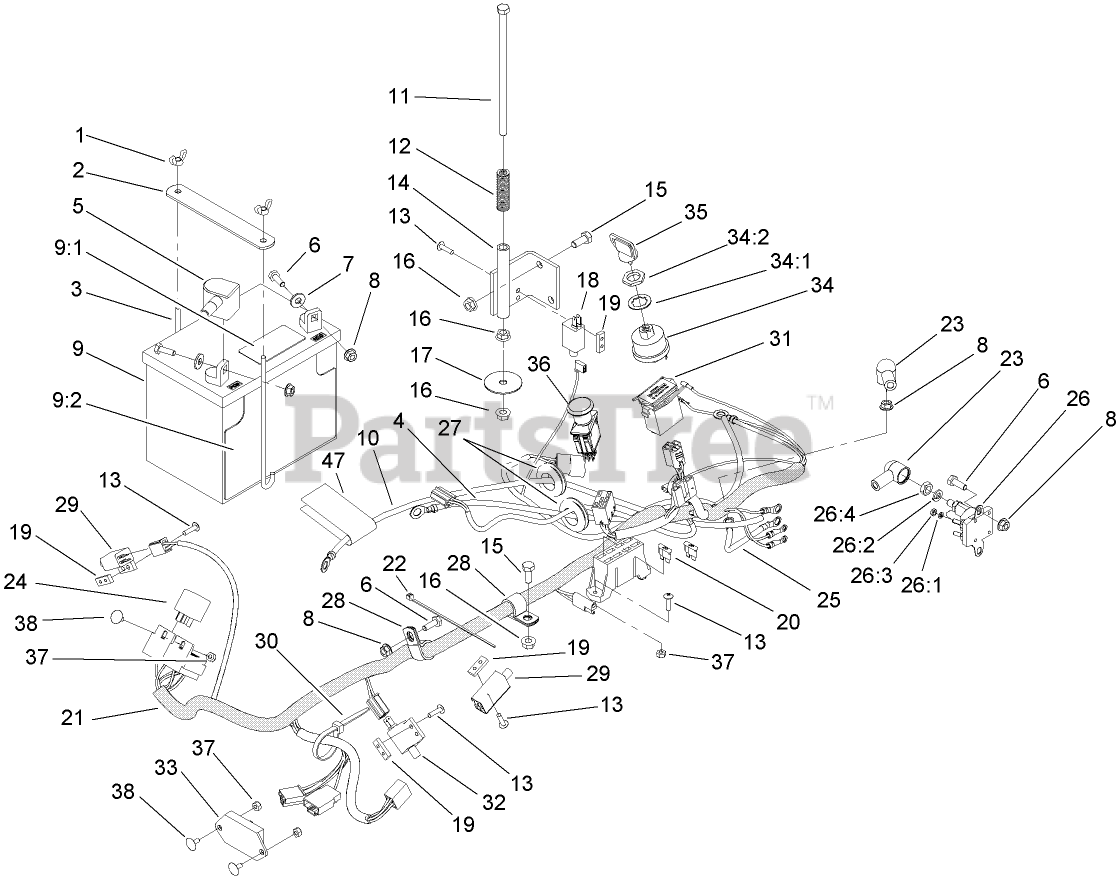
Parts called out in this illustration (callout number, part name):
1	WINGNUT
2	STRAP-HOLDDOWN, BATTERY
3	BOLT-HOLDDOWN
4	CABLE-GROUND, NEGATIVE
5	INSULATOR-BATTERY
6	SCREW-HH
7	WASHER-FLAT
8	NUT-HF
9	BATTERY
9:1	Decal-Battery
9:2	Decal-Battery
10	CABLE-BATTERY, POSITIVE
11	SCREW-HH
12	SPRING-SWITCH, SEAT
13	SCREW-HEAD, TRUSS
14	BRACKET-SWITCH, SEAT
15	SCREW-HH
16	NUT-HF
17	WASHER
18	SWITCH-CLOSED, NORMALLY
19	PLATE-TAPPED
20	FUSE-BLADE TYPE, 20 AMP
21	HARNESS-ELECTRICAL
22	TIE-CABLE
23	INSULATOR-SOLENOID
25	CABLE-STARTER, POSITIVE
26	SWITCH-SOLENOID
26:1	WASHER-LOCK
26:2	WASHER-LOCK
26:3	NUT-HEX
26:4	NUT-JAM
27	GROMMET
28	CLIP-LOOM
29	SWITCH-OPEN, NORMALLY
30	TIE-PLASTIC
31	METER-HOUR
32	SWITCH
33	MODULE-DELAY, SEAT
34	SWITCH-STARTING, KEY
34:1	WASHER-TOOTH, INTERNAL
34:2	NUT-HH
35	KEY-IGNITION
36	SWITCH-PTO
37	NUT-LOCK, NI
38	BOLT-CARR
47	DECAL-INSTRUCTIONS, CHARGING
